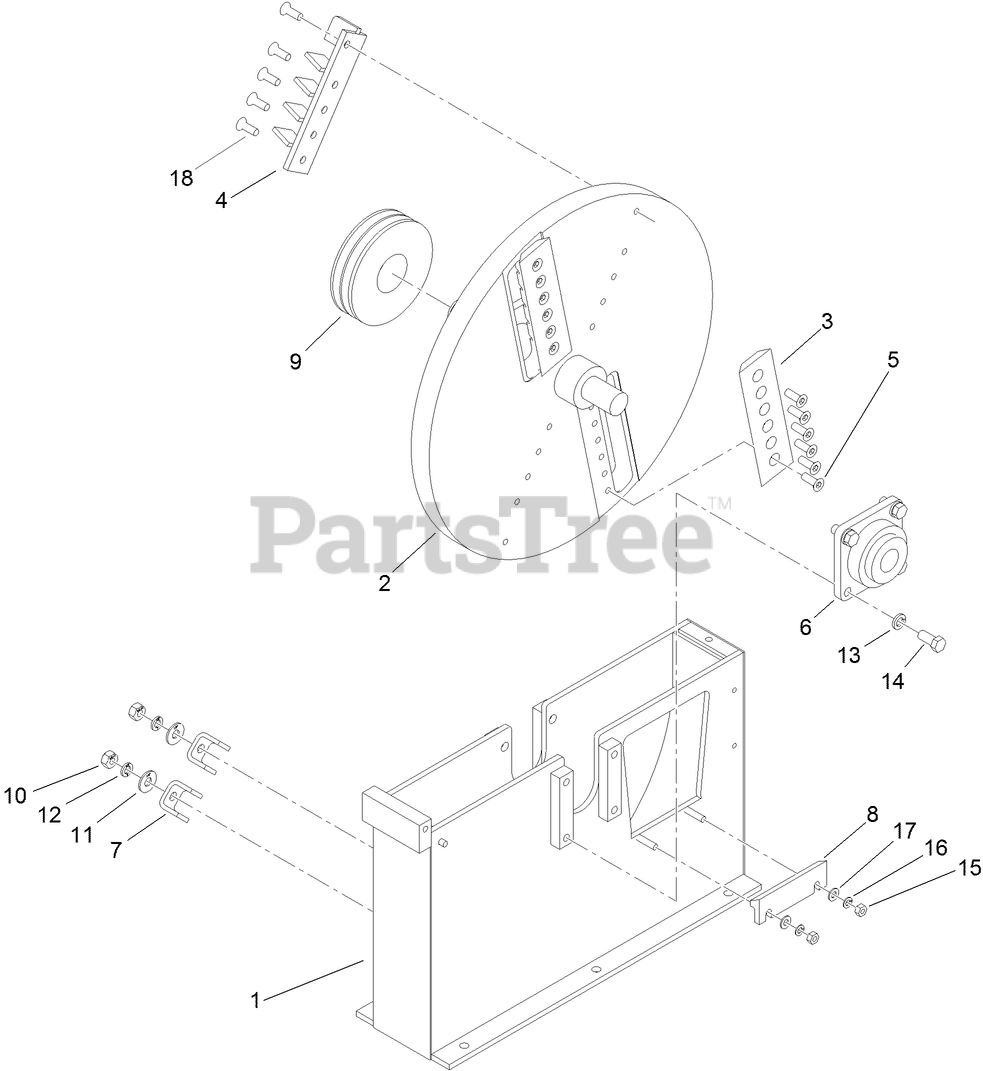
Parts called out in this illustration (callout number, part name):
1	CHASSIS ASM
2	FLYWHEEL ASM
3	BLADE-CHIPPER
4	CHOPPER ASM
5	SCREW-HSFH
6	BEARING ASM
7	PLATE-CHOPPER, STATIONARY
8	BLOCK-CUTTER
9	PULLEY ASM
10	NUT-HEX
11	WASHER-FLAT
12	WASHER-LOCK
13	WASHER-LOCK/SP
14	SCREW-HH
15	NUT-HEX
16	WASHER-LOCK
17	WASHER-FLAT
18	BOLT-HSFH
